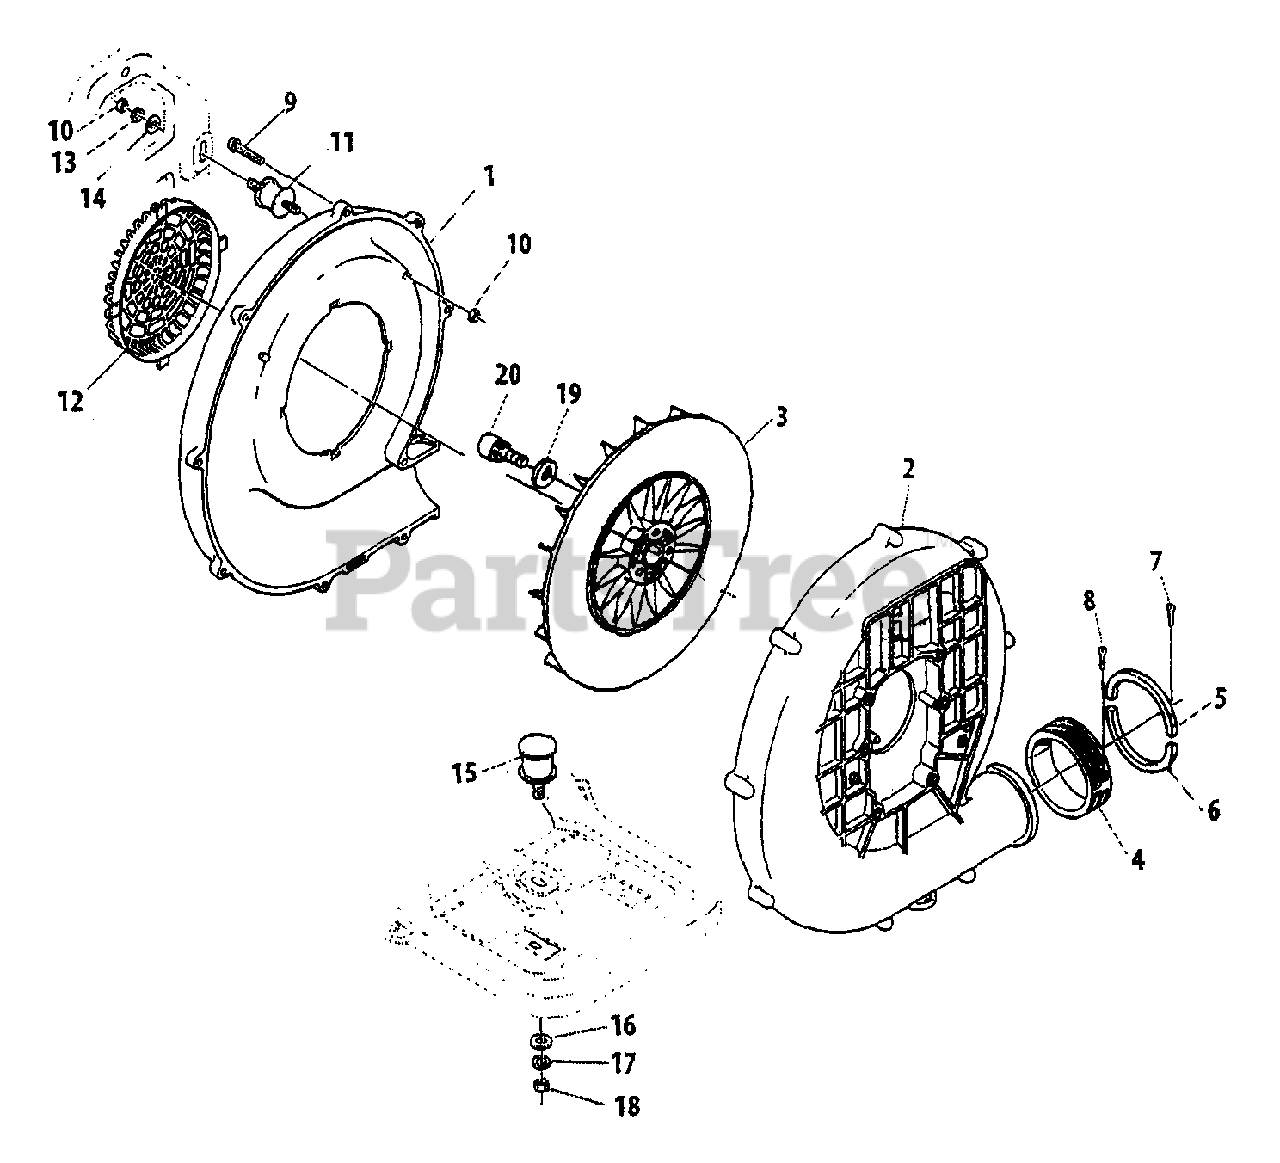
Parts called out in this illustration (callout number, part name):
1	COVER, FAN - INNER
2	COVER, FAN - OUTER
3	FAN, BLOWER
4	SLEEVE
5	RETAINING RING (A)
6	RETAINING RING (B)
7	SCREW
8	SCREW, TAPPING
9	BOLT, TAPPING 5
10	NUT M5
11	CUSHION 5
12	COVER, INTAKE
13	WASHER, SPRING 5
14	WASHER 5
15	CUSHION 6
16	COLLAR Ø18ר6.4×L2
17	WASHER, SPRING 6
18	NUT, HEX M6
19	WASHER 6
